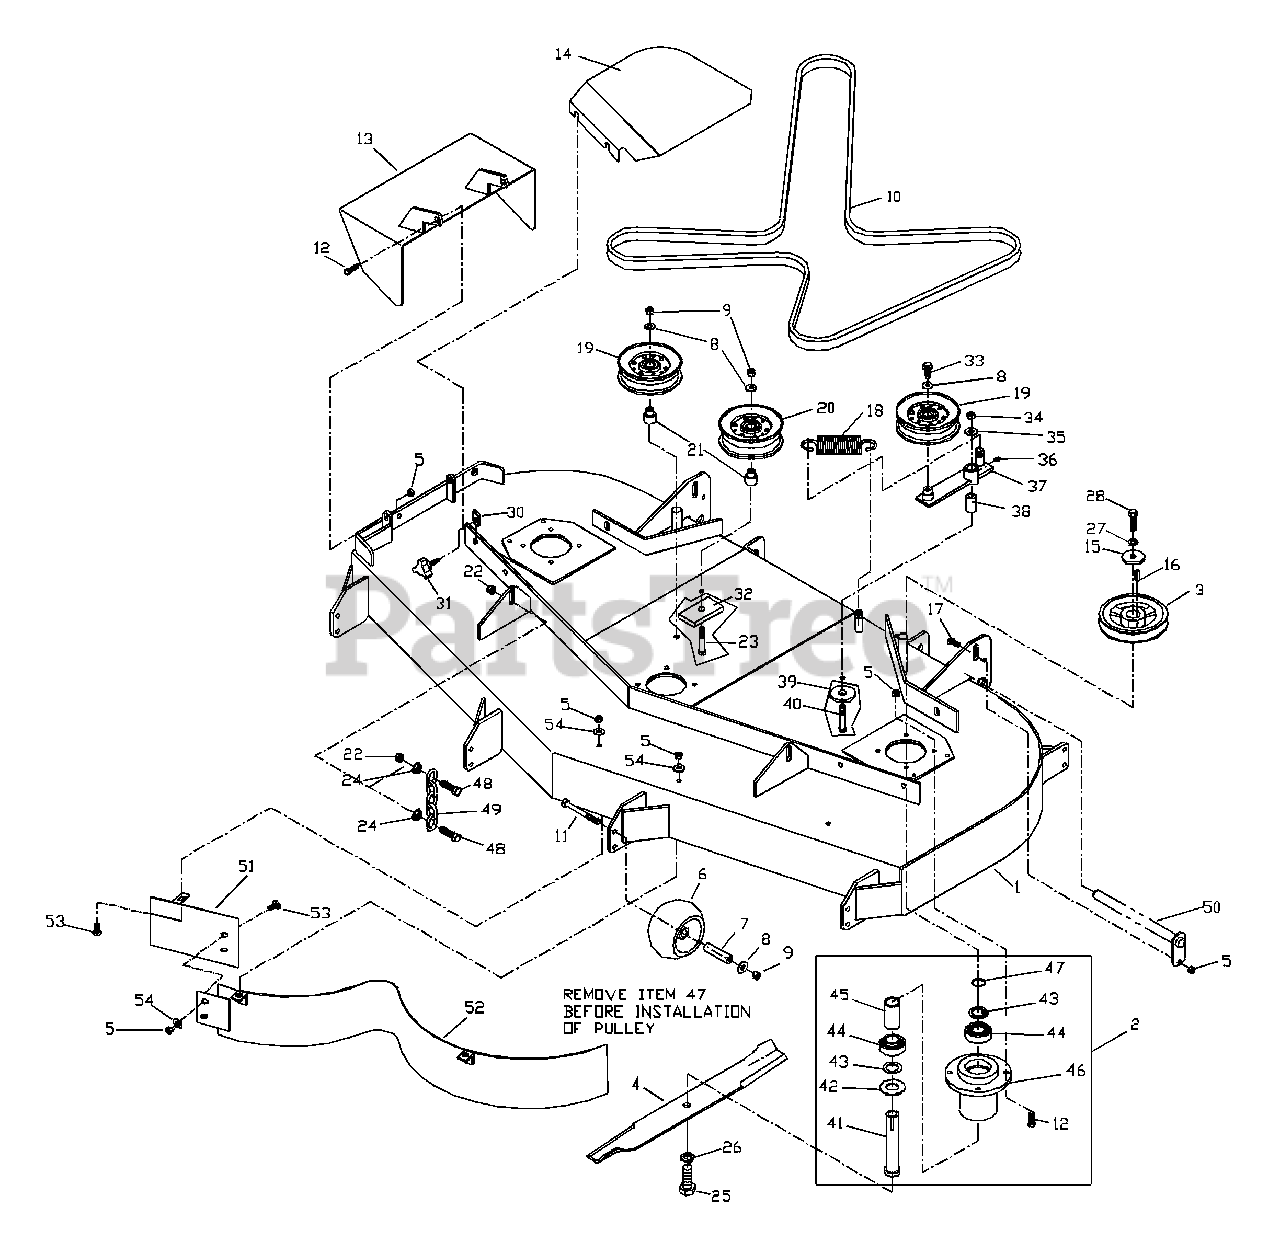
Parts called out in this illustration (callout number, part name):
1	61" DECK W/ DECALS
1	52" DECK W/ DECALS
2	CUTTER HOUSING ASM.
3	PULLEY 61" DECK
3	PULLEY 52" DECK
5	NUT 5/6C CENTERLOCK
8	WASHER 3/8 STD.
9	NUT 3/8C CENTERLOCK
10	BELT 61"
10	BELT 52"
11	HCS 3/8C X 3.5
12	HCS 5/16C X 1
13	DISCHARGE CHUTE
14	BELT SHIELD RT. 61"
14	BELT SHIELD RT. 52"
16	KEY 1/4SQ. X 1 1/8
17	HCS 5/16C X 3/4
19	IDLER PULLEY (1.31)
20	IDLER PULLEY (1.62)
21	IDLER BUSHING
22	NUT 7/16C CENTERLOCK
23	HCS 3/8C X 2.5
24	7/16C WHIZ NUT
25	HCS 5/8F X 1.25
27	7/16 LOCK WASHER
28	HCS 7/16F X 1.5
29	BELT SHIELD LT. 61"
29	BELT SHIELD LT. 52"
31	KNOB W/ STUD
32	PAD
33	HCS 3/8C X 1 SERR.
34	NUT 1/2C NYLOC
35	1/2 FLAT WASHER
36	ZERK
38	PIVOT BUSHING
39	SUPPORT WASHER
40	HCS 1/2C X 3.25
42	MACH. BUSHING 10GA.
43	MACH. BUSHING 18GA.
44	BEARING
48	HCS 7/16C X 1.5
49	LIFT CHAIN
51	CENTER BAFFLE 52"
51	CENTER BAFFLE 61"
52	MAIN BAFFLE 52"
52	MAIN BAFFLE 61"
53	CARRIAGE BOLT
54	5/16 FLAT WASHER
